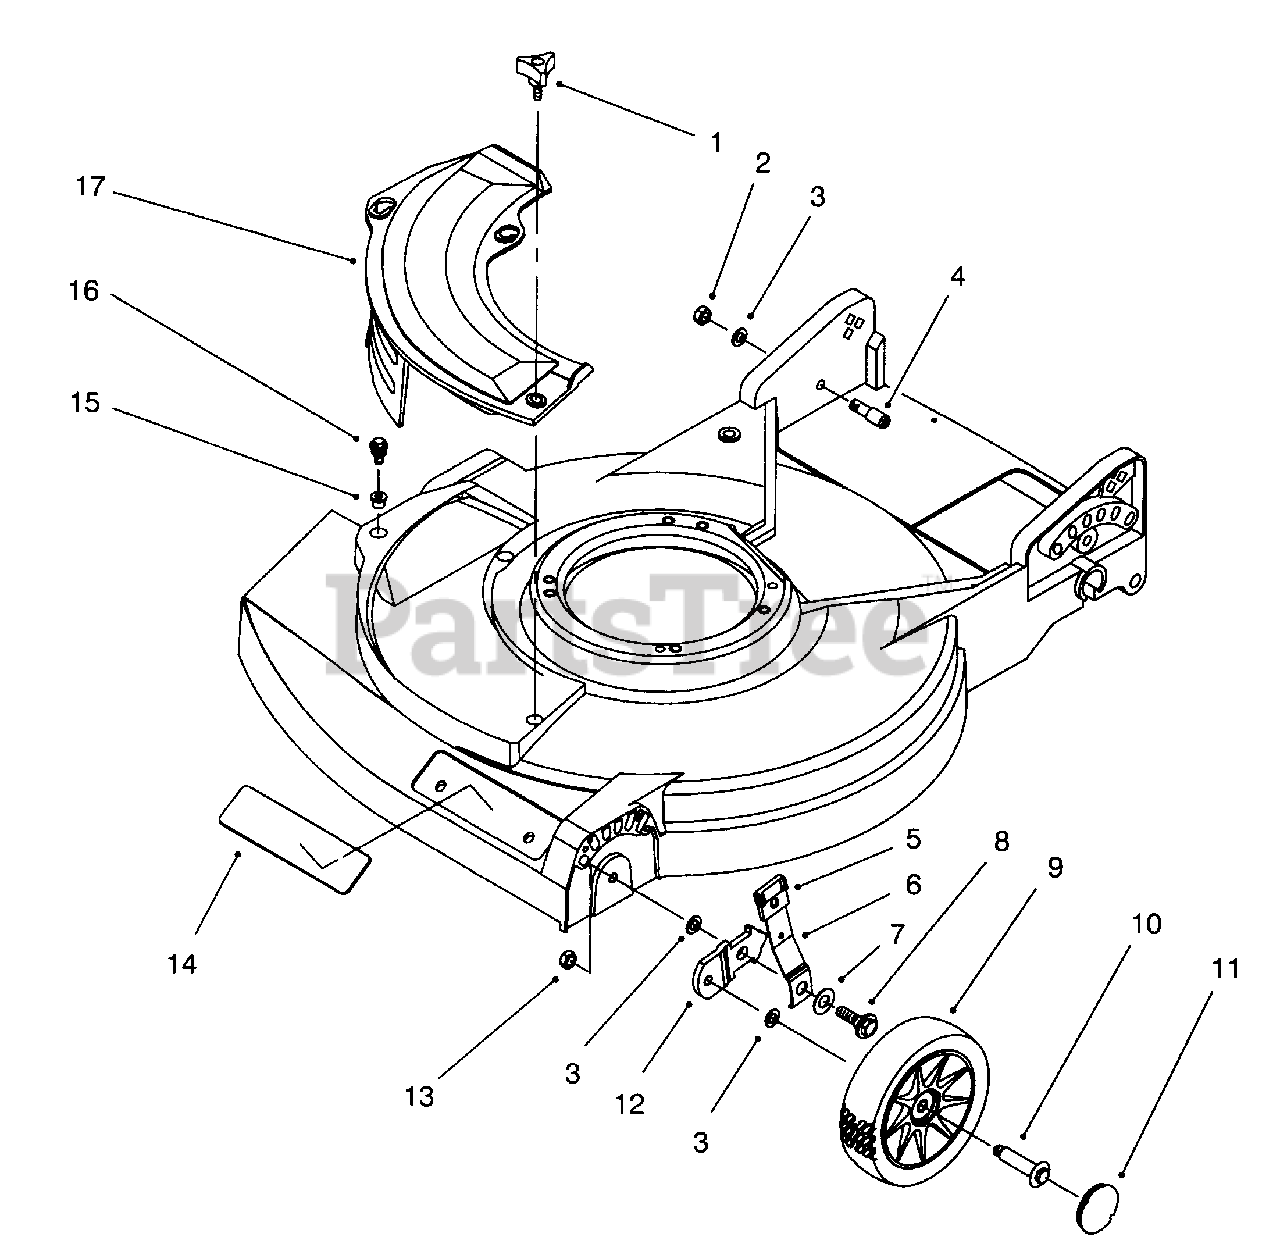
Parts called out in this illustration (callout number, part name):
1	Knob-Cover Plate
2	Nut-Lock
4	Bolt-Shoulder
5	Knob-Height Adjust
6	Spring Arm Ass'y-Front
7	Washer-Belleville
8	Bolt-Shoulder
9	Wheel & Tire Assembly 6"
10	Bolt-Shoulder
12	Bracket-Wheel Height Adj.
13	Nut-Lock
14	Decal-Deck
16	Screw-Sems Thr'd Form.
17	Plate-Mulch
